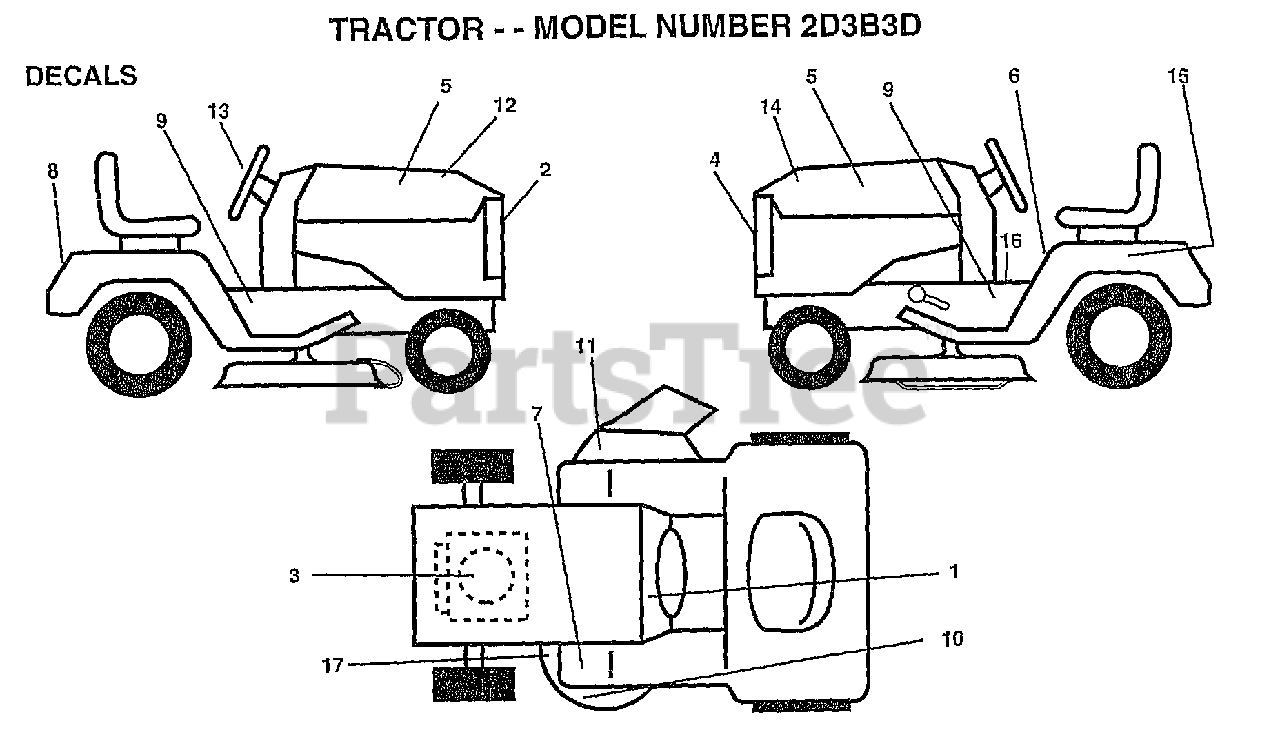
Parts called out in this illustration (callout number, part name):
1	DECAL.DASH.INSTR.
2	GRILL DECAL
3	DECAL, HP ENGINE
5	DECAL.HOOD.INSERT
6	DECAL CAUTION
7	DECAL T
8	FENDER DECAL
11	"DECAL, WARNING"
12	DECAL HOOD RH RLY
13	"DECAL,STR WHL"
14	DECAL HOOD LH RLY
15	DECAL.BTRY.DANGER
16	DECAL BRAK PARK
17	DECAL
